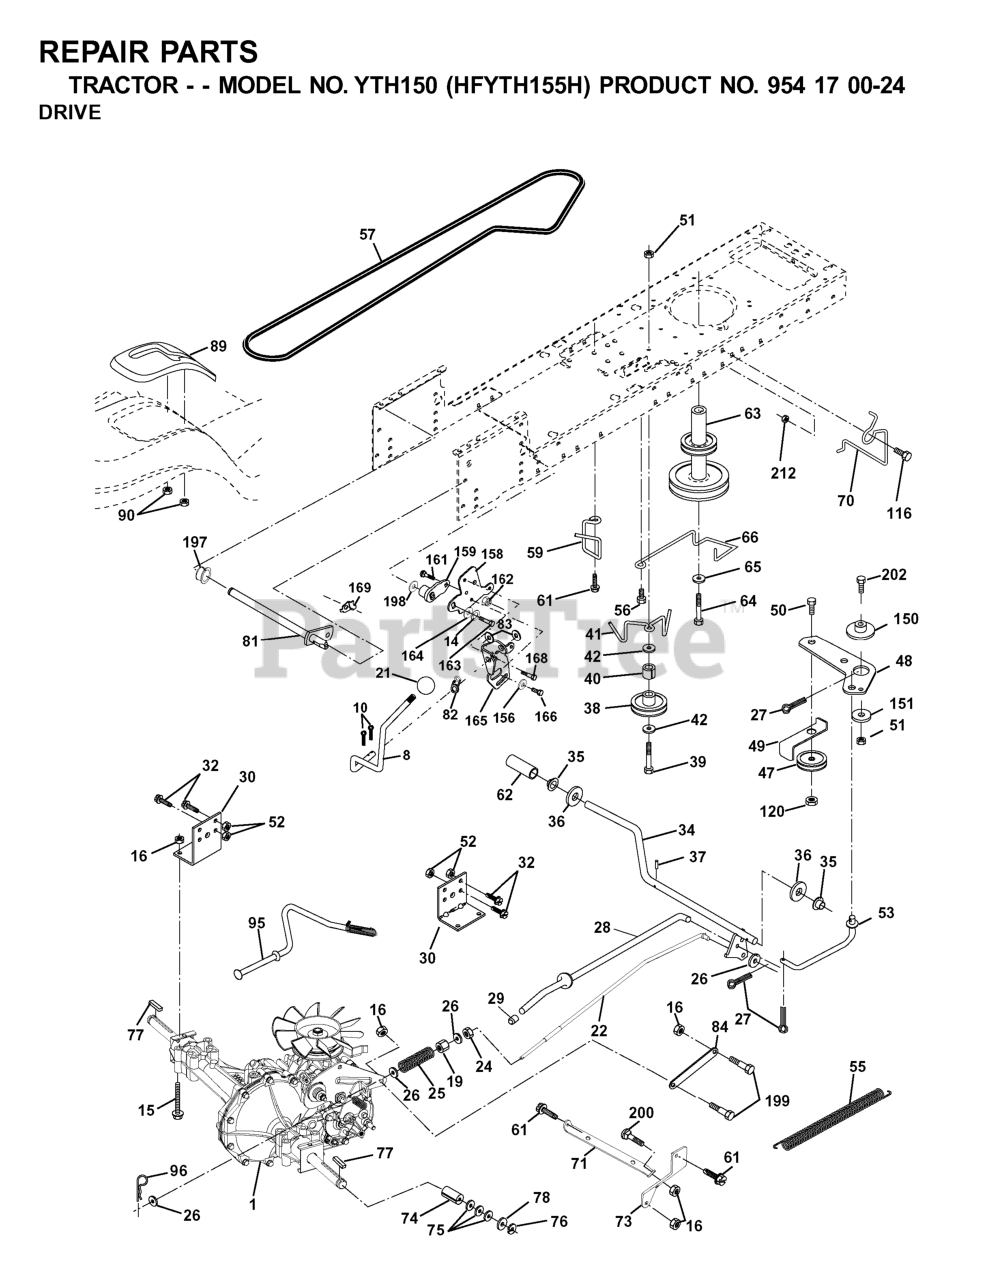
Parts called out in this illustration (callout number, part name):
8	ROD SHIFT FENDER ADJUST STLT
10	PIN COTTER
14	LOCKWASHER
15	BOLT HEX 5/16-18 GR 5
16	NUT.71038.31-18.HEX.NYLOCK
19	NUT
21	KNOB.DUCKHEAD.1/2
22	ROD BRAKE HYDRO
24	NUT
25	SPRING ROD LT
26	WASHER
27	COTTER PIN
28	ROD, PARKING BRAKE
29	PLUNGER CAP
30	BRKT, TRNSXLE MNT 20"
32	BOLT
34	SHAFT, FOOT PEDAL
35	BEARING.NYLON
37	DRIVE PIN
38	PULLEY.FLAT
39	BOLT
40	SPACER, SPLIT
41	KEEPER, BELT IDLER
42	WASHER
47	IDLER PULLEY
48	BELLCRANK, CLUTCH
49	RETAIN BELT
50	BOLT
52	LOCKNUT
53	LINK, CLUTCH LT
55	SPRING, RETURN LT
56	SCREW THDROL 3/8-16 X 1-1/2
57	DRIVE BELT, LTH & YTH TRACTORS
59	KEEPER, BELT CENTER
61	SCREW 3/8-16X3/4
62	COVER, PEDAL (1 2)
63	ENGINE PULLEY
64	BOLT
65	LOCKWASHER
66	KEEPER BELT ENGINE
70	KEEPER BELT ENG
71	STRAP TORQUE LH HYDRO
72	WASHER
73	STRAP TORQUE RH HYDRO
74	SPACER AXLE
77	SQUARE KEY
81	SHAFT ASM CROSS TAPERED
82	SHIFT SPRING
83	WASHER
84	LINK TRANSAXLE
89	SHIFT CONSOLE
90	NUT.PUSH.3/16
95	CONTROL ASM. BYPASS HYDRO
96	RETAINER M
116	BOLT D
120	NUT LOCK FLG 3/8-16 UNC
150	SPACER, RETAINER
151	WASHER 12/32X2X10GA
156	WASHER.SRRTD.5/16
158	BRACKET
159	HUB
161	BOLT
162	NUT.CROWNLOCK.1/4
164	Washer 5/8 x .281 x 10 Ga.
165	RP BRACKET
168	BOLT.SHOULDER.5/16-18X
169	PLATE.FASTENING.CROSS.SHAFT
197	NYLINER SNAP 5/8" ID
198	WASHER.NYL.7/8IDX.105"HYD CR
199	BOLT SHOULDER 5/16-18 UNC
202	BOLT.3/8-16X1.50
212	NUT
